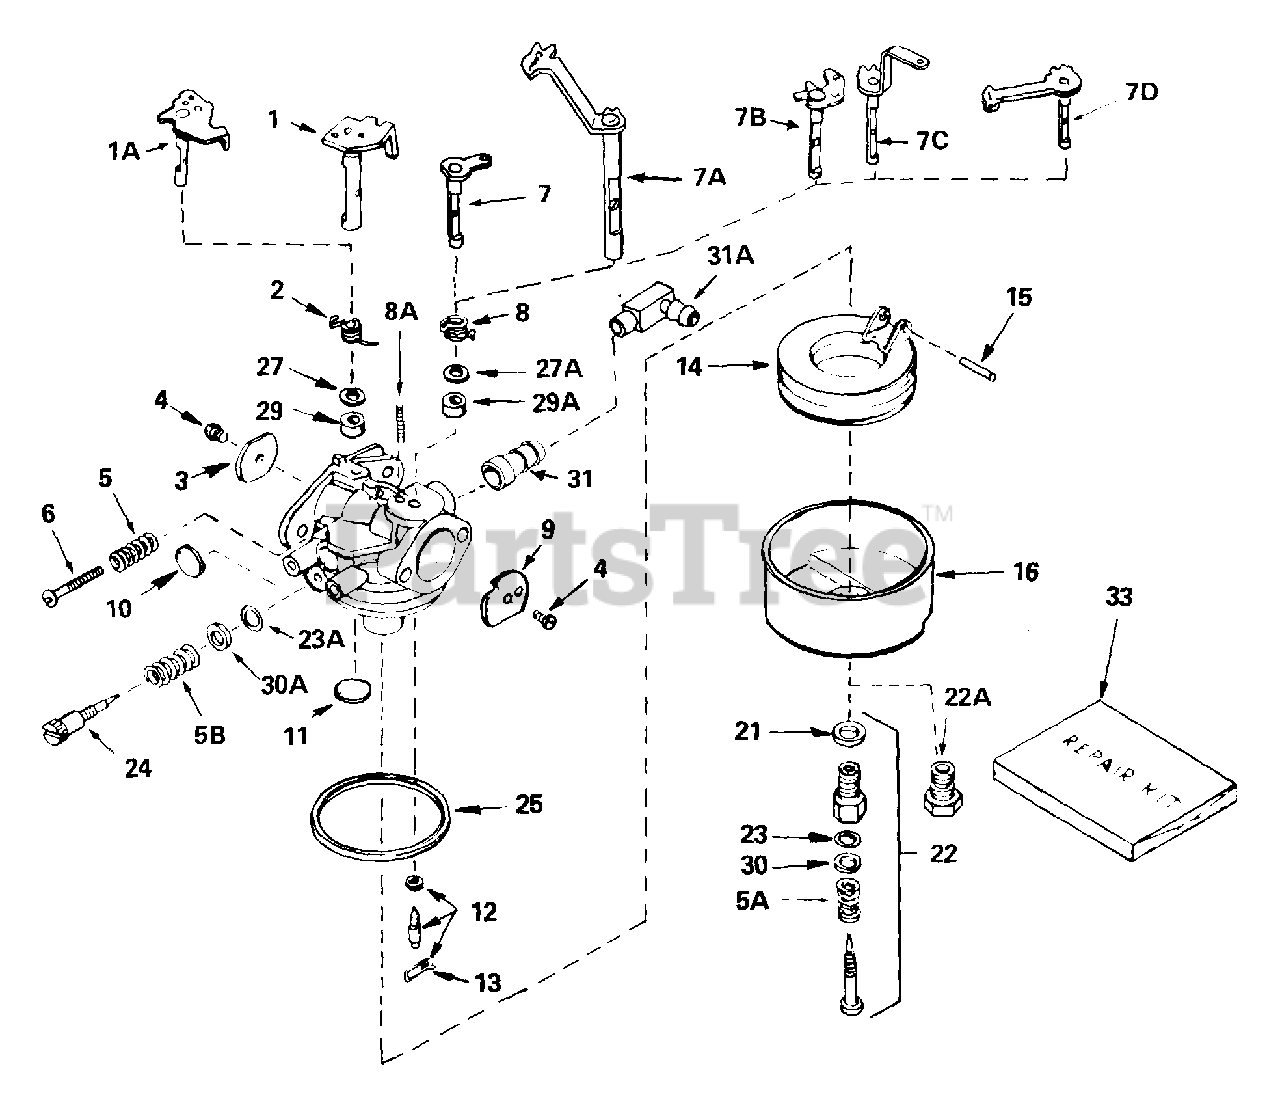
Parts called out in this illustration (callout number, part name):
1	"Shaft & Lever Assy., Throttle
2	Spring, Throttle return
3	Shutter, Throttle
4	Screw, Throttle & Choke shutter
5	Spring, Adj.
5A	Spring, Adj. screw
5B	Spring, Adj. screw
6	Screw, Idle regulating
7D	Shaft & Lever Assy., Choke
8	Spring, Compression
8A	Spring, Choke positioning
9	Shutter, Choke
10	Plug, Welch
11	Plug, Welch
12	Inlet Needle, Seat & Clip Assy.
13	Clip, Inlet needle
14	Float, Carburetor
15	Shaft, Float
16	Bowl, Float
21	Gasket, Bowl-to-body
22	Adj. Screw Assy., Main
23	"O" Ring, Adj. screw
23A	"O" Ring, Adj. screw
24	Screw, Idle adj.
25	Gasket, Bowl-to-body
29	Seal, Dust
29A	Seal, Dust
30	Washer, Flat
30A	Washer, Flat
31	Fitting, Fuel
33	Repair Kit
